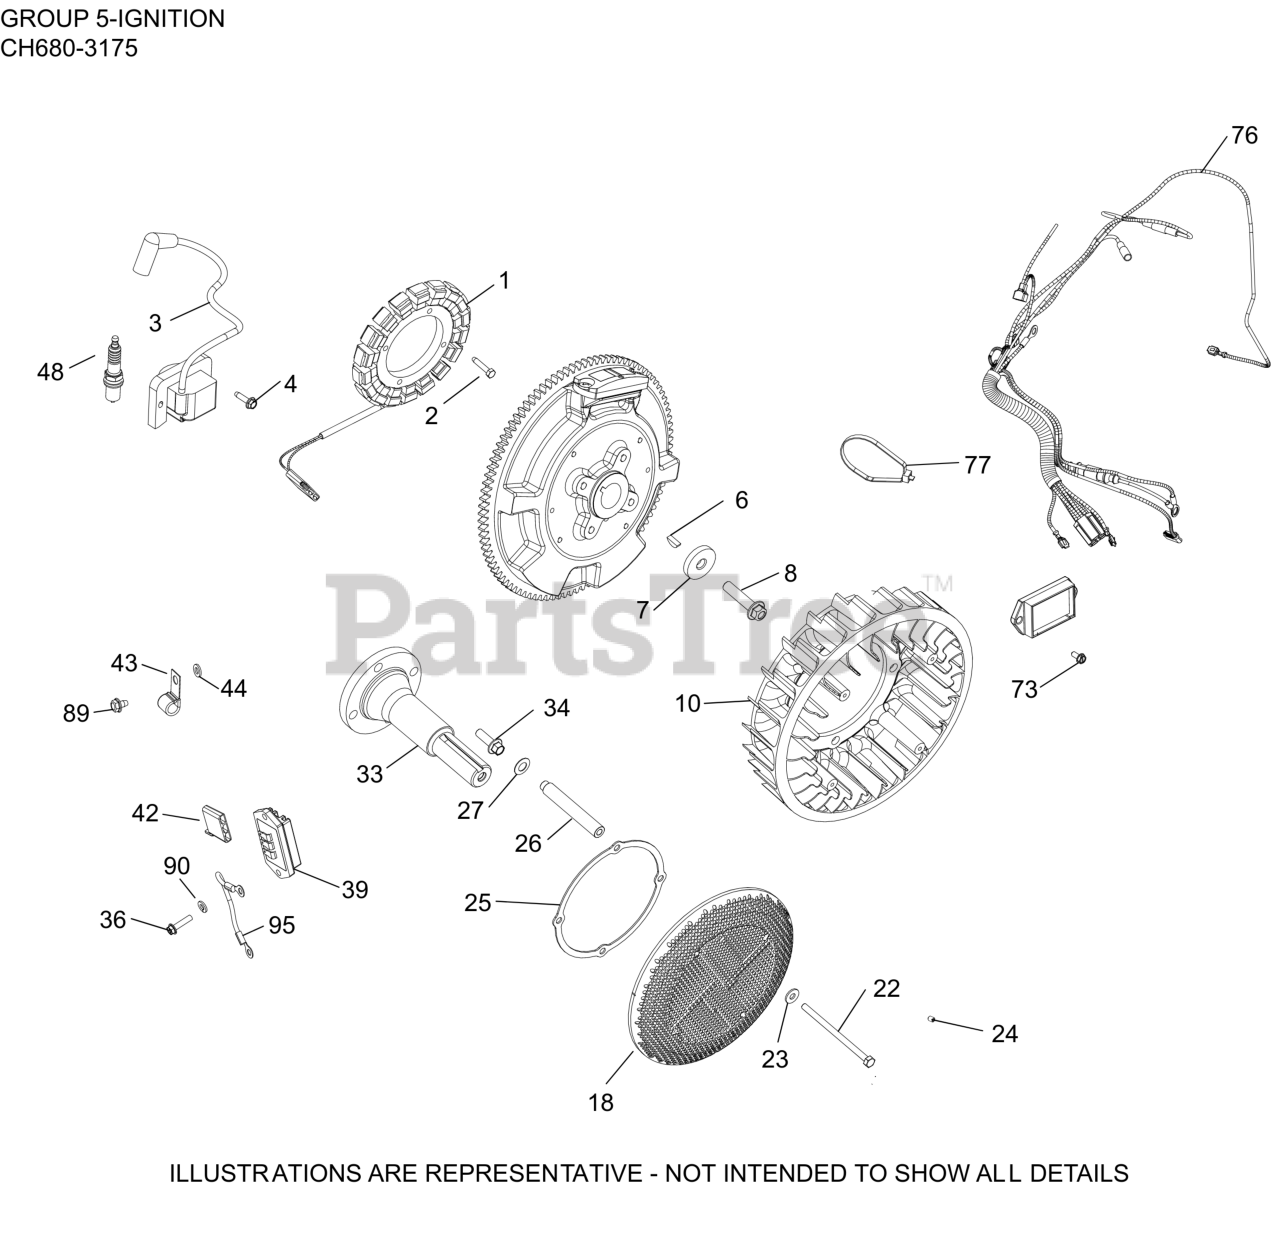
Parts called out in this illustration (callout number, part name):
1	KIT, 15 / 20 AMP STATOR
2	SCREW, THREAD FORMING
3	MODULE, EMC/RFI COMPLIANT
4	SCREW, THREAD FORMING
6	KEY, 3/16" X 5/8"
7	WASHER, FLAT
8	SCREW, HEX FLANGE
10	FAN-USE 24 755 253-S
18	SCREEN, GRASS
22	SCREW, CAP M6X1.0X99.5
23	WASHER, FLAT 1/4" (O.D. 5/8")
24	SCREW, SKT SET #10-24X1/4"
25	RING, SUPPORT
27	WASHER, SPRING 10 MM
33	SHAFT, FRONT DRIVE
34	SCREW, FLG M8X1.25X25
36	SCREW, HEX FLANGE HI-LO
39	REGULATOR/RECT 12/15A-(#2540345S)
42	CONNECTOR
43	CLIP, CABLE
44	WASHER, FLAT 1/4" (O.D. 1/2")
48	SPARK PLUG, RFI
73	SCREW, WSH HD TAP #8-18X1/2"
76	HARNESS, WIRING ASSEMBLY
89	SCREW, THREAD FORMING
90	WASHER, LOCK
NI	FLYWHEEL ASSEMBLY (LW, 22)
